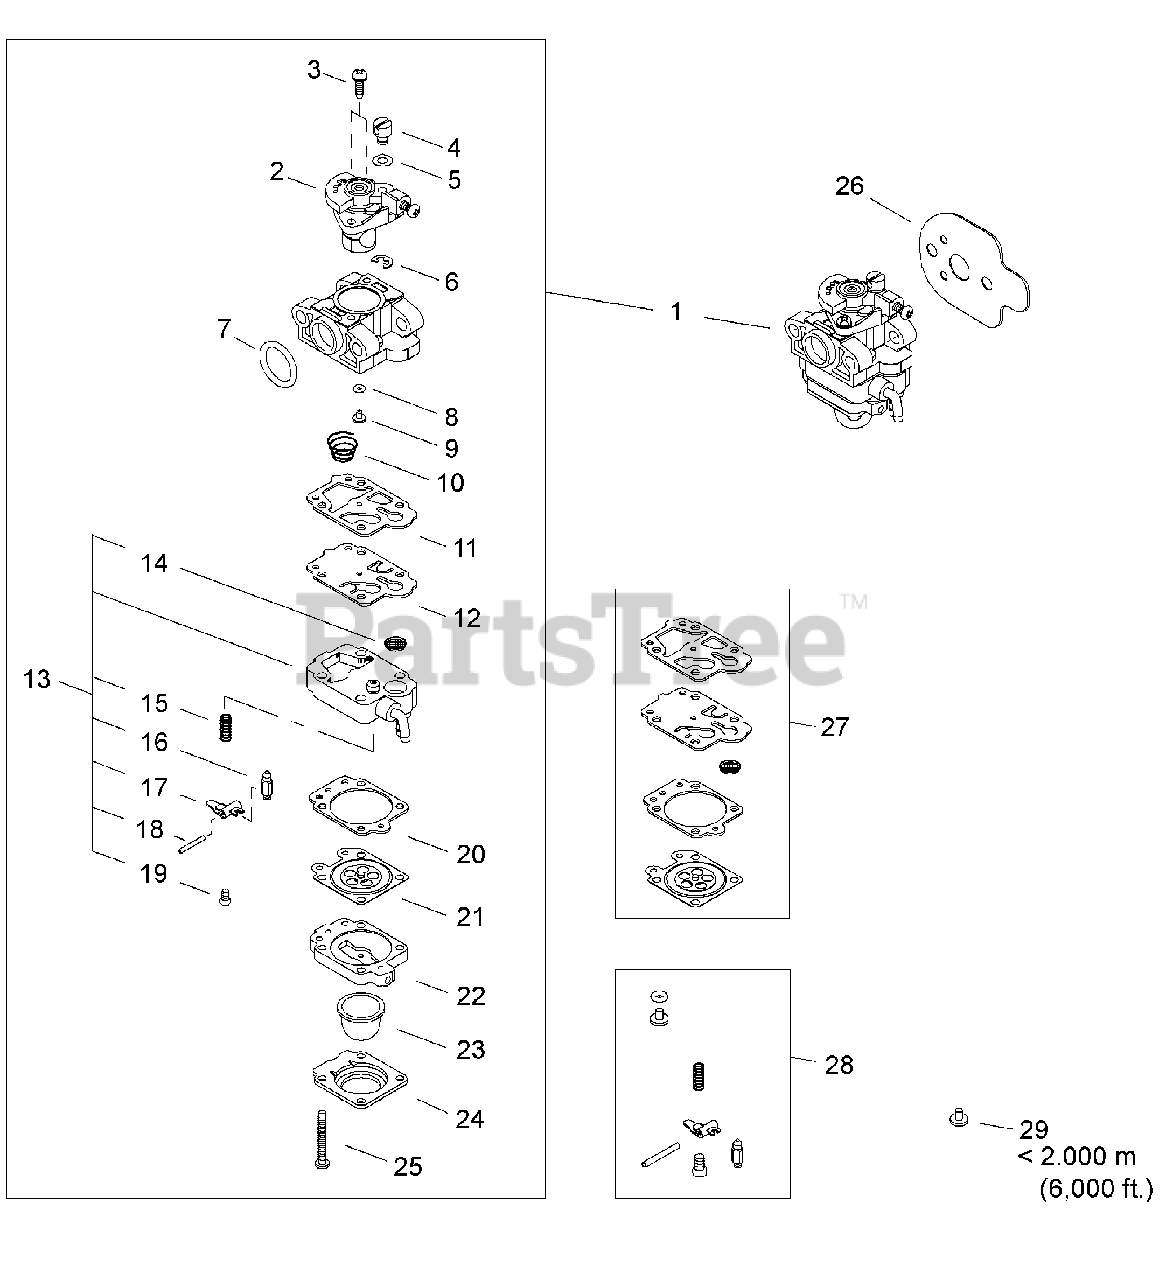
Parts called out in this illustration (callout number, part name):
1	CARBURETOR
2	THROTTLE VALVE ASSY
3	SCREW
4	SWIVEL
5	WASHER
6	RING, RETAINING
7	O-RING - 15
8	O-RING
9	JET, MAIN - 1000M #40
11	GASKET, PUMP
12	DIAPHRAGM, PUMP
13	PUMP BODY ASSY
14	STRAINER
15	SPRING, METERING LEVER
16	VALVE, INLET NEEDLE
17	LEVER, METERING
18	PIN, METERING LEVER
19	SCREW, METERING LEVER PIN
20	GASKET, METERING
21	DIAPHRAGM, METERING
22	BASE, PURGE
23	BULB, PURGE
24	RETAINER, PURGE BULB
25	SCREW, PUMP COVER
26	GASKET, INTAKE
27	DIAPHRAGM/GASKET KIT
28	INLET NEEDLE VALVE KIT
29	MAIN JET - 2000M #38
